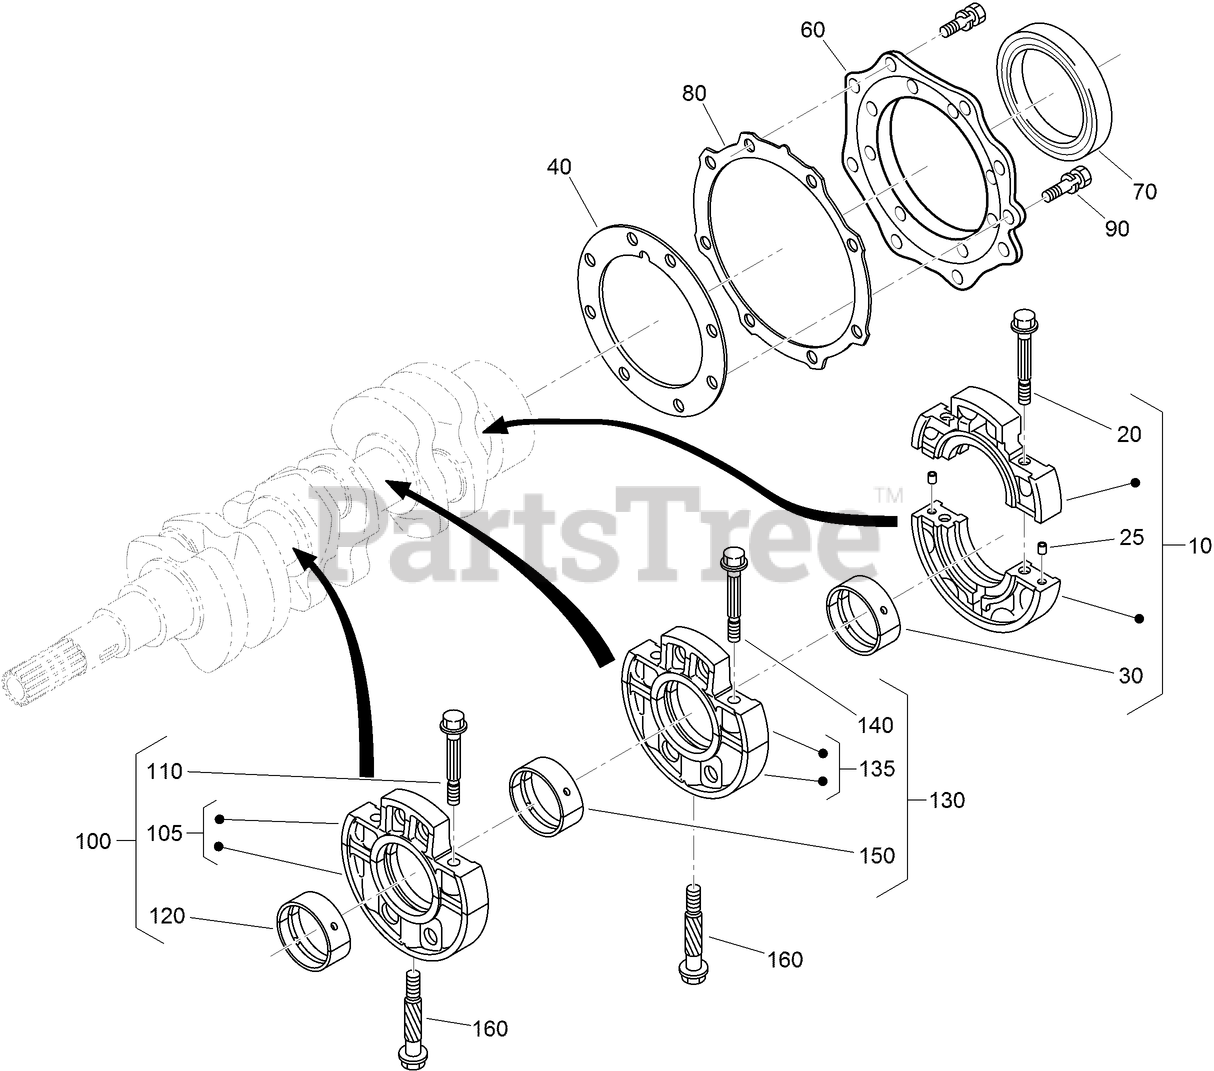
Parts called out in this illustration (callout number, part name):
10	WHEEL BEARING CASE ASM
20	BOLT-FLANGE
25	PIN-STRAIGHT
30	METAL-CRANKSHAFT
30	CRANKSHAFT-METAL (-0.2MM SET)
40	GASKET-CASE, BEARING
60	COVER-CASE, BEARING
70	SEAL-OIL
80	GASKET-COVER, CASE
100	BEARING CASE ASM
105	MAIN BEARING CASE ASM
110	BOLT-CASE, BEARING
120	METAL-CRANKSHAFT
130	BEARING CASE ASM
135	MAIN BEARING CASE ASM
140	BOLT-CASE, BEARING
150	METAL-CRANKSHAFT
160	BOLT-CASE, BEARING
